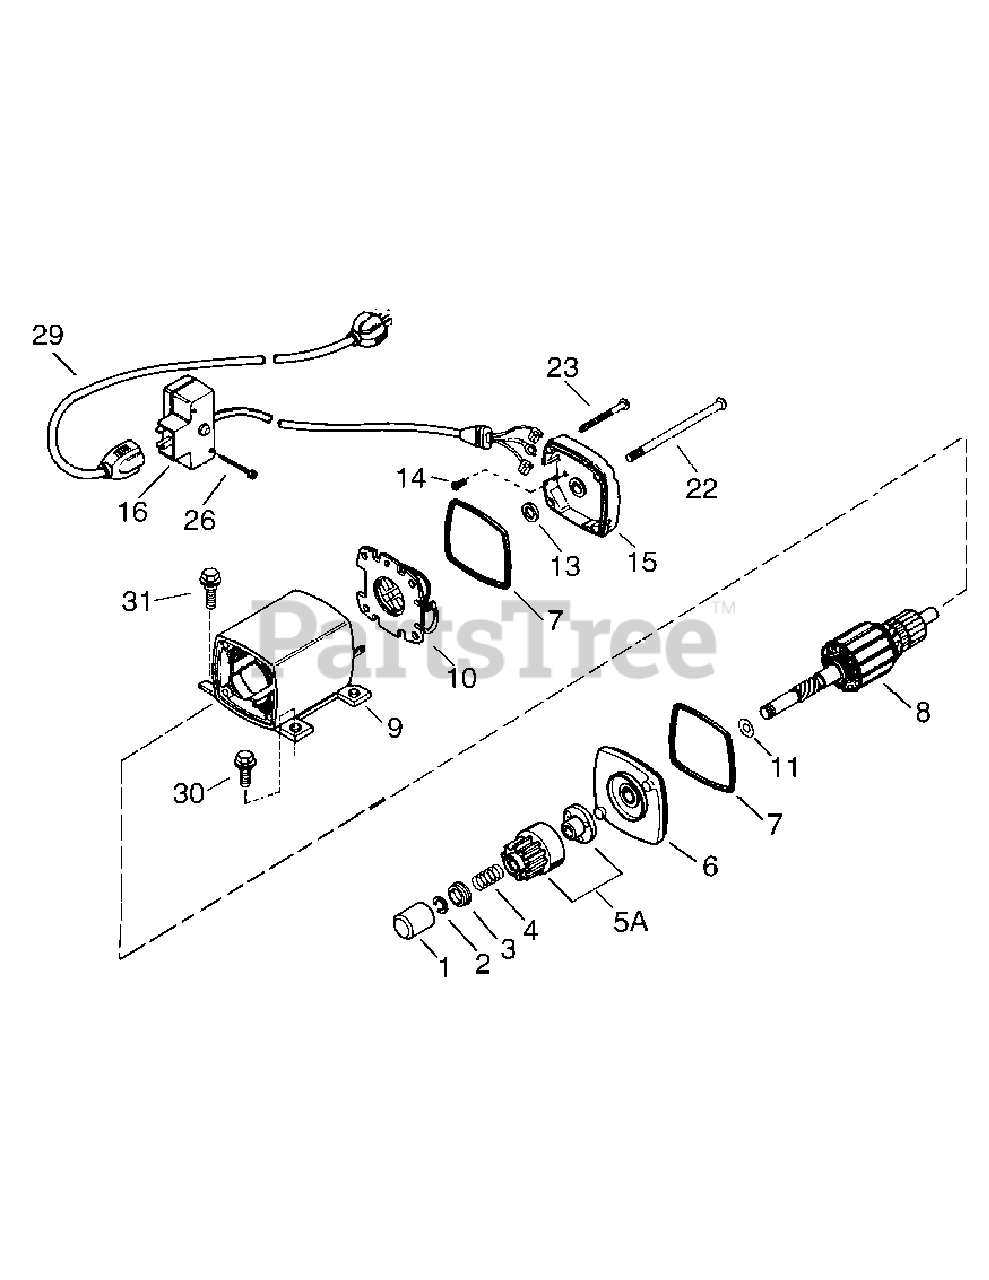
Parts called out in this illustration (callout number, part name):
1	Dust Cover
2	Retainer Ring
3	Spring Retainer
4	Anti-drift Spring
5A	Gear & Nut (Incl. 2)
6	Drive End Cap Ass'y. (Incl. 7)
9	Housing Ass'y.
10	Brush Card Ass'y.
11	Thrust Washer
13	Thrust Washer
14	Ground Screw
15	Commutator End Cap Ass'y. (Incl. 7)
16	Switch Box Ass'y.
22	Case Bolt
23	Ground Screw
26	Screw, 6-32 x 2-1/2"
26	Screw, 12-16 x 5/8"
29	Extension Cord (10' 6")
30	Screw, T-30, 1/4-20 x 1/2"
31	Screw, 1/4-20 x 1/2"
